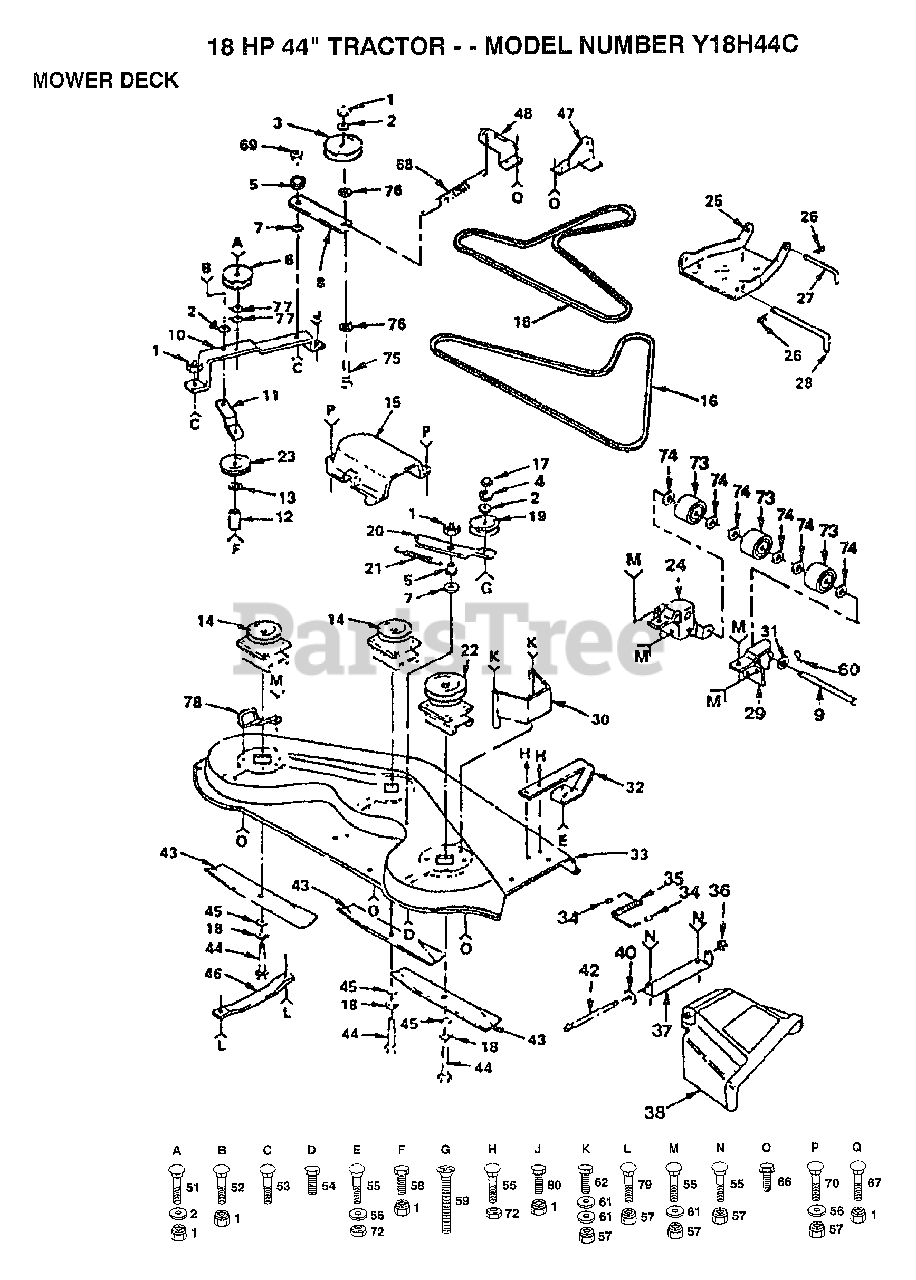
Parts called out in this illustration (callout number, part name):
2	WASHER
3	PULLEY IDLER
4	LOCKWASHER
5	SPACER RETAINER
6	IDLER-INSIDE T
7	"WASHER, WEAR LT"
8	ARM IDLER
9	PIVOT PIN T
10	"SUPPORT YT, BAR"
11	BRACE-IDLER YT
12	SPACER
13	WASHER
15	GUARD YT
16	BELT-V.79.1.MWR
17	NUT.HEX.3/8-16UNC
19	IDLER.FLAT.GTV
20	ARM-IDLER YT
23	IDLER-FLAT T
24	BRACKET LH YTH
25	LINK.PARALLEL
26	SPRING.RETAINER
27	"ROD, FRT. PARAL T"
28	HINGE PIN T
29	BRACKET RH YTH
30	GUARD BELT HYT
32	RUNNER.RH
34	CAP-SLEEVE LT
35	SPRING TORSION
36	NUT PUSH M
37	BRKT DEFLECTOR
38	DEFLECTOR SHIELD
40	WASHER
42	ROD-HINGE T
44	BOLT.3/8-24X1-1/2
45	WASHER
46	RUNNER-LH M
47	BRKT SUSP REAR RH
48	BRKT SUSP REAR LH
51	BOLT
53	BOLT
55	BOLT
56	WASHER
58	BOLT - HEX 3/8 - 16 X 3
59	SCREW YT
60	COTTER PIN
61	WASHER M
62	BOLT
66	SCREW
67	BOLT
68	"SPRING.EXT.8.5"""
69	LOCKNUT
73	ROLLER T
74	WASHER T
75	BOLT
76	WASHER
77	WASHER
78	BELT RETIANER
79	BOLT
80	BOLT
